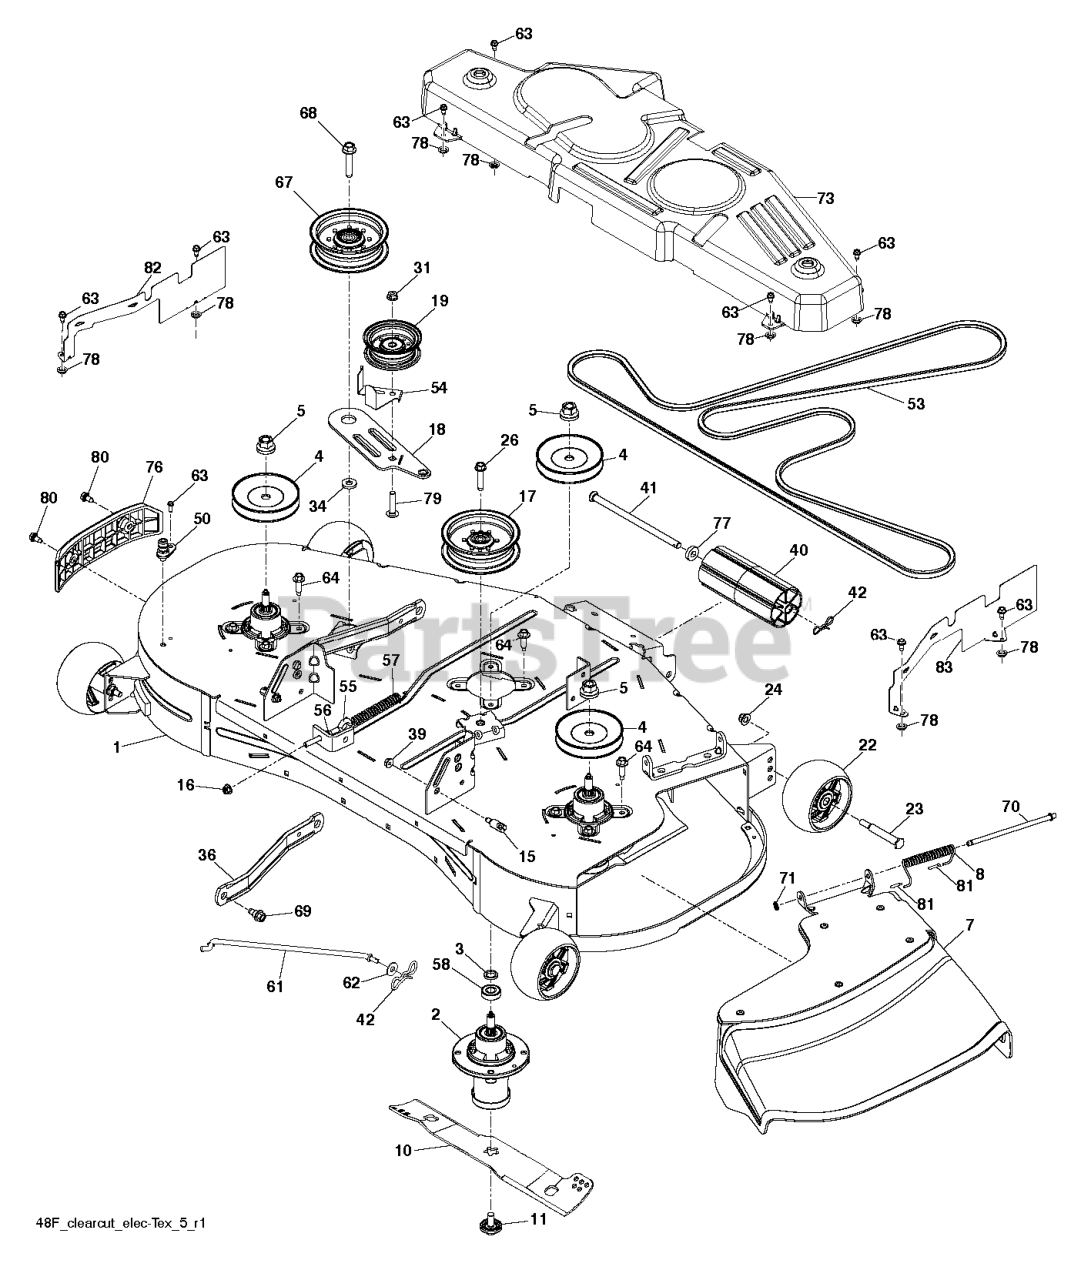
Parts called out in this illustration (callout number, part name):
1	DECK KIT.SVC.48.CC.ASM.668
2	MANDREL ASM, CAST IRON
3	WASHER.SPACER.MANDREL
4	MANDREL PULLEY
5	NUT.FLANGE.LOCK.TOP
7	DEFLECTOR.ASM.48".CLRCT.RES.OR
8	SPRING.42.FCS.DEFLECTOR
10	BLADE.48.CC.EURO.RES.BGR.MS431
11	BOLT.WASHER.ASM.7/16-2
15	STUD.FASTNER.W/ANTI-ROTATE
16	5/16-18 NYLOC FLANGE NUT
17	PULLEY.IDLER.MWR.STATI.LH
18	ARM.PNT.CLUTCHING.ASM.EDIP
19	PULLEY.IDLER.48"PRIMARY
22	WHEEL.GAUGE.RALLY
23	BOLT.SHOULDER.3/8-16X3-5/8.
24	NUT 3/8-16 HEX FLG NYLOC ZD
26	SCREW.7/16-14 X 2.125.WASHER
31	NUT LOCK FLG 3/8-16 UNC
36	ARM.SUSPENSION.MOWER
39	NUT LOCK HEX FLANGE 5/16-18
40	NOSE ROLLER 48"
41	ROD.ROLLER.NOSE.NARROW.48"
42	PIN.COTTER.5/16.BOW TI
50	PORT.WASHOUT
53	BELT.DECK.TRACTOR
54	GUARD, BELT
55	EYE BOLT 5/16 X 3.50
56	NUT 5/16C WHIZ
57	SPRING.EXTN.42.FCS.TR.DECK.DRV
61	ROD.ANTI.SWAY.48/54"TE
62	WASHER
63	PIN.COTTER.5/16.BOW TI
64	BOLT.HEX.WASHR.HED.313-18X1.19
67	PULLEY.IDLER.2006
68	SCREW LT
69	BOLT.SHOULDER
70	ROD.HINGE
71	NUT PUSH M
73	COVER 48 CLEARCUT EURO TRACTOR
76	BUMPER 48 CLEARCUT TRIM SIDE A
77	BUSHING.NOSE.ROLLER
78	PALNUT 1/4
80	SHOULDER BOLT 5/16-18TT
81	CAP-SLEEVE LT
82	SHIELD 48 CLEARCUT EURO TRACTO
83	SHIELD 48 CLEARCUT EURO TRACTO
